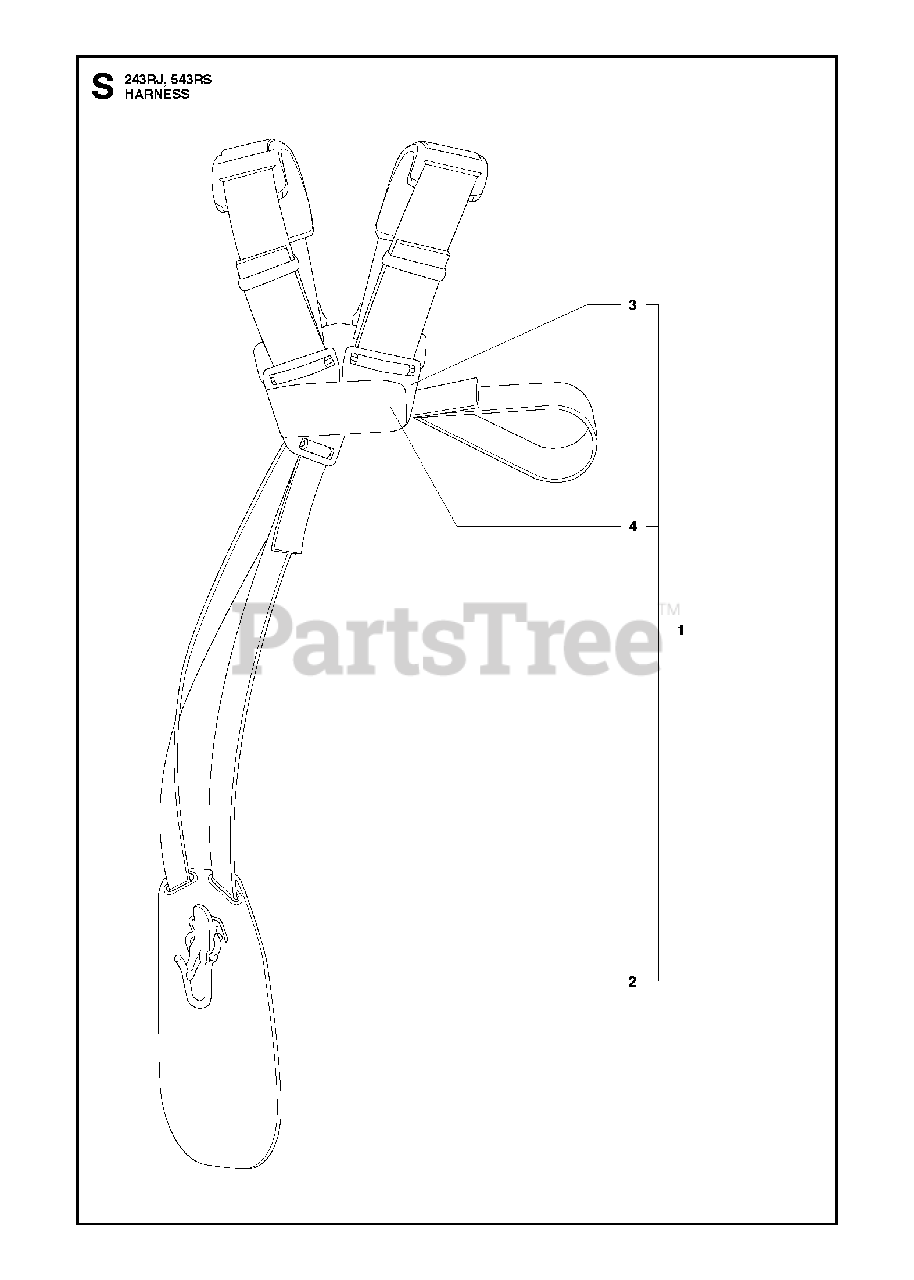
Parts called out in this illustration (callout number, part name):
1	HARNESS DUO
2	HOOK, CPL.
3	BUCKLE
4	STRAP
